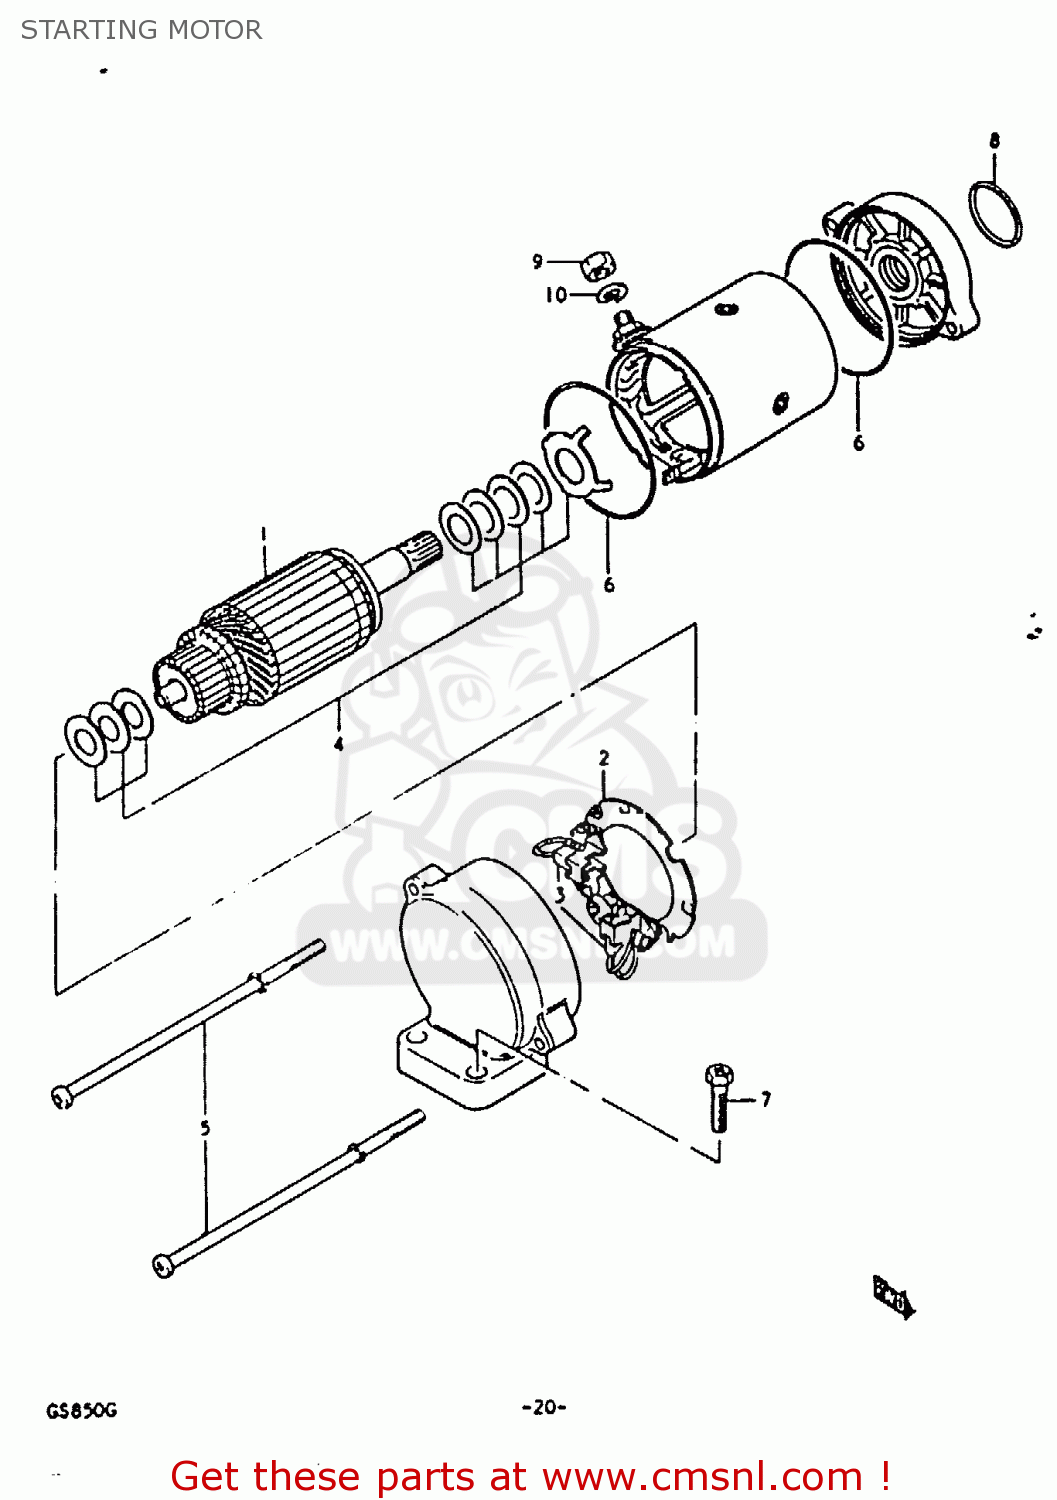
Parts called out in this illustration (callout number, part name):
1	ARMATURE
2	HOLDER ASSY
3	BRUSH SET
4	SHIM SET
5	BOLT,STARTING MOTOR HOUSING
6	O RING
7	SCREW
8	O RING(D:2,ID:24.5)
9	NUT 6MM
10	LOCK WASHER
